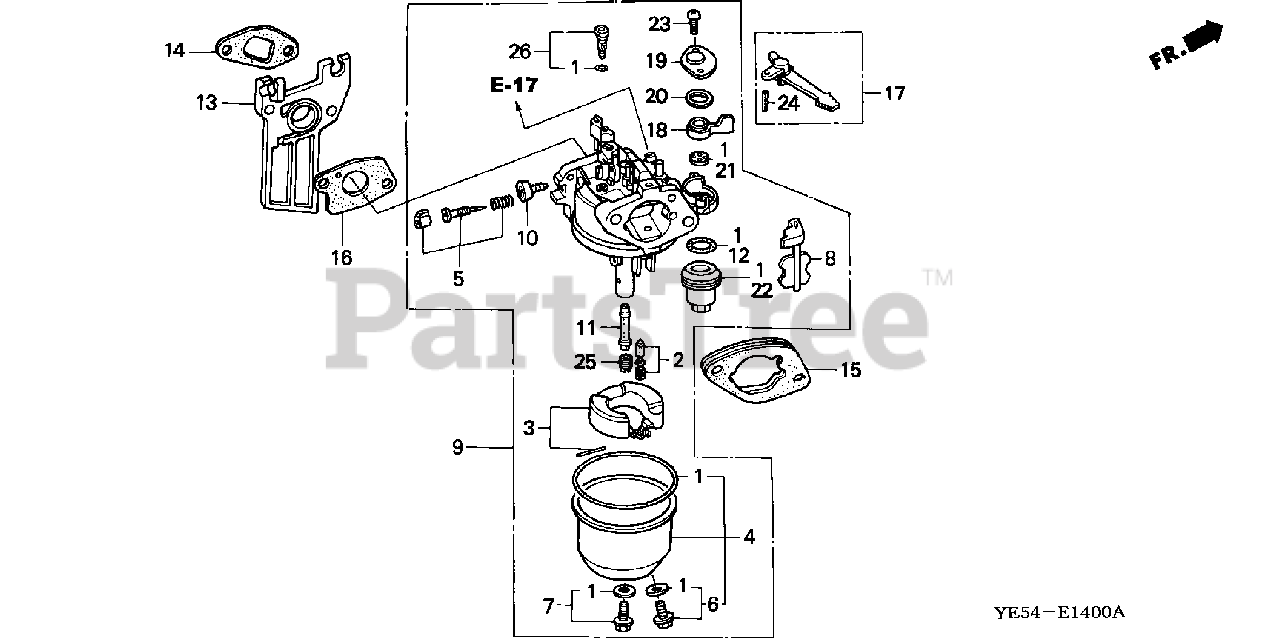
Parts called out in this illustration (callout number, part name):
1	GASKET SET
2	VALVE SET, FLOAT
4	CHAMBER SET, FLOAT
6	SCREW SET, DRAIN
7	SCREW SET B
9	CARBURETOR ASSY. (BE65C B)
10	SCREW, THROTTLE STOP
11	NOZZLE, MAIN
12	GASKET, FUEL STRAINER CUP
13	INSULATOR, CARBURETOR
14	GASKET, INSULATOR
15	SPACER, CARBURETOR
16	GASKET, CARBURETOR
17	LEVER, CHOKE (STD)
18	LEVER, VALVE
19	PLATE, LEVER SETTING
20	SPRING, VALVE LEVER
21	GASKET, VALVE
22	CUP, FUEL STRAINER
23	SCREW, PAN (3X6)
23	SCREW, PAN (3X8)
24	PIN, SPRING (2X12)
25	JET, MAIN (#65)
25	JET, MAIN (#68)
25	JET, MAIN (#70)
26	JET SET, PILOT (#35)
